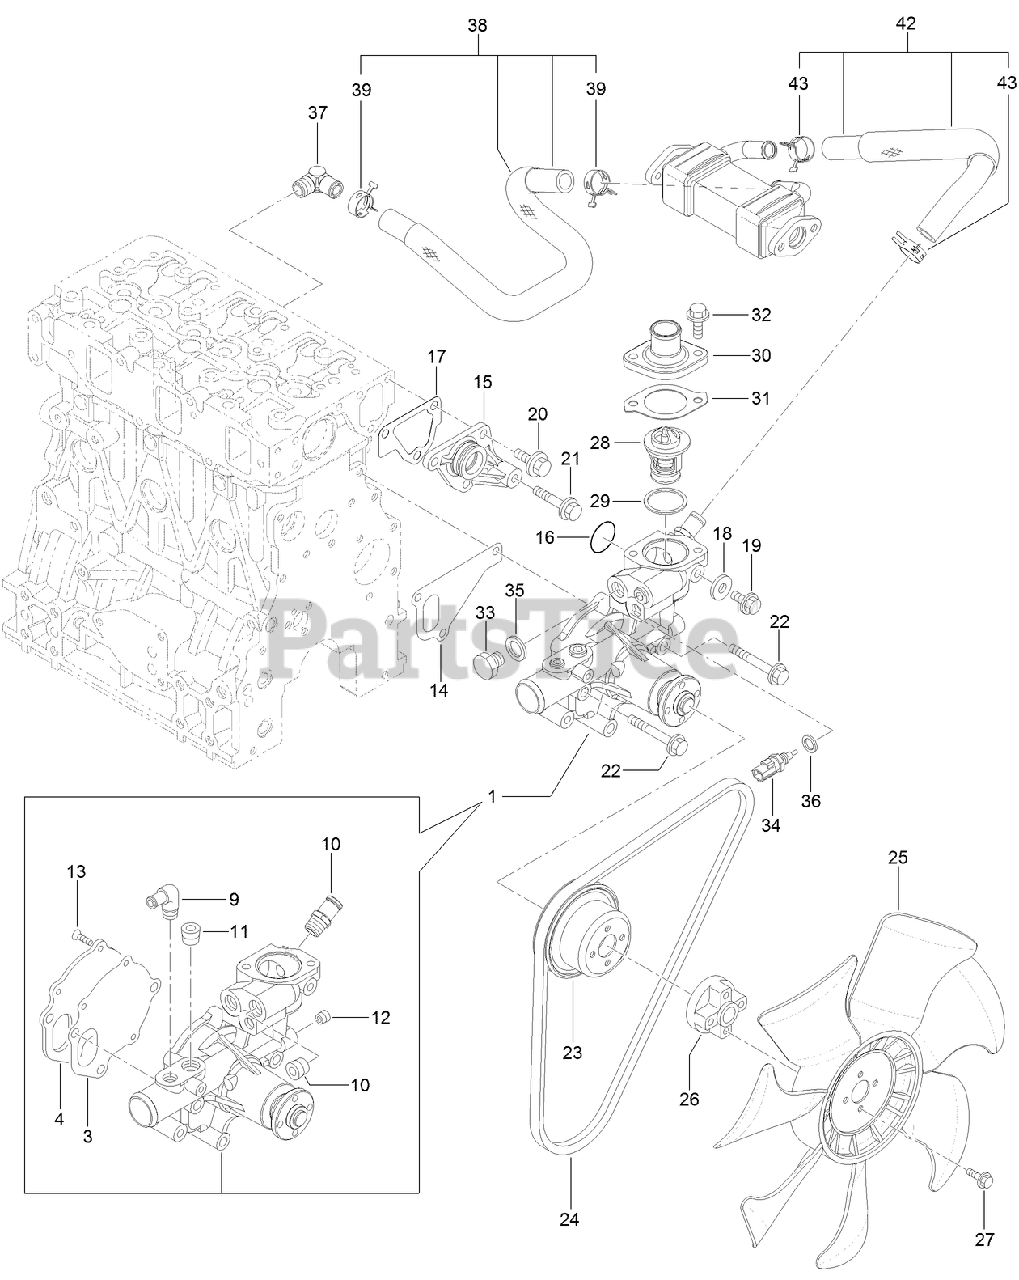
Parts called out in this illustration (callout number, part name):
1	WATER PUMP ASM
3	GASKET
14	GASKET
16	O-RING
17	GASKET
18	GASKET
20	BOLT
23	V-PULLEY
24	V-BELT
26	SPACER
28	THERMOSTAT
29	GASKET
31	GASKET
34	SENSOR-THERMOSTAT, CW
35	GASKET
36	WASHER-SEAL
38	E G R-C PIPE ASM
39	CLIP-HOSE
42	CW PIPE ASM
43	CLIP-HOSE
